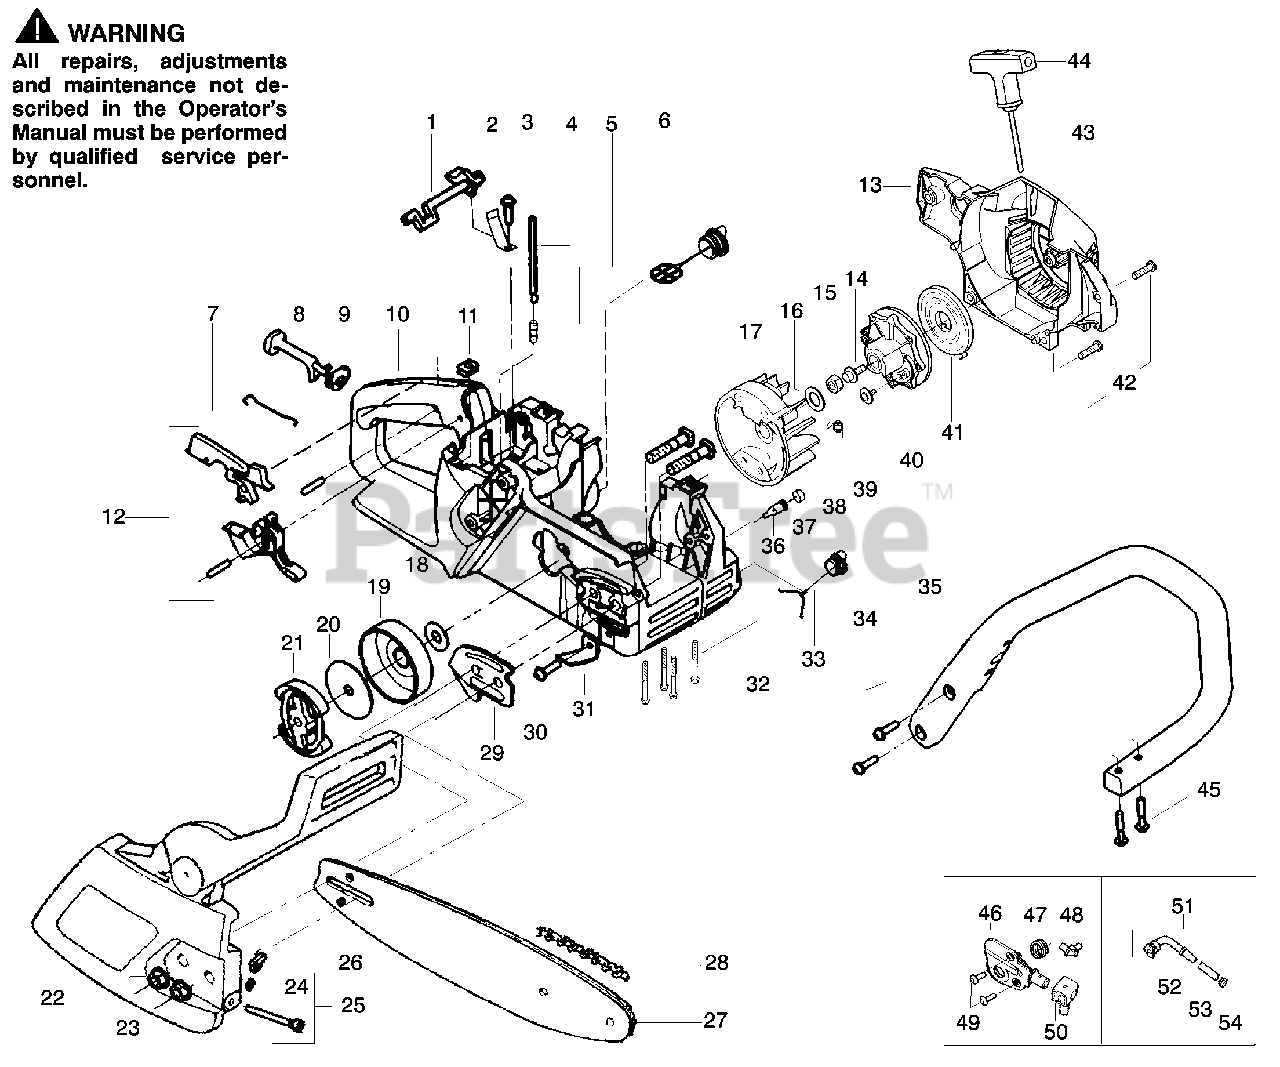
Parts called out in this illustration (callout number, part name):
1	Lever-Switch
2	Spring-Switch
4	Kit-Fuel Line (Large)
6	Assy-Fuel Cap
7	Wire-Throttle
8	Lever-Choke
9	Grommet-Choke Knob
10	Assy-Chassis
11	Nut-Speed
12	Kit-Trigger & Lockout
13	Housing-Fan
15	Nut-Flywheel
16	Washer-Flywheel
17	Assy-Flywheel
18	Washer - Thrust
19	Assy-Drum W/brg.
20	Washer-Clutch
21	Assy. - Clutch
22	Assy-Chain Brake
23	Nut-Bar Mounting
24	Retainer-Bar Adjust
25	Kit-Bar Adjust
26	Pin-Bar Adjust
27	Bar-18"
28	Chain-18"
29	Plate-Bar Mounting
31	Chain Catcher
33	Assy-Oil Cap
35	Handle-Front
36	Valve-Check
37	Plug - Bronze Vent
38	Spring - Starter Dog
40	Pulley-Starter
41	Spring-Starter
43	Kit-Rope
44	Handle-Starter
46	Kit-Oil Pump
47	Gear-Worm Spring
48	Elbow-Oil Pickup
50	Seal Block
51	Assy-Oil-Pickup
52	Pickup-Oiler
53	Filter-Oil
54	Plug-Oil Filter
